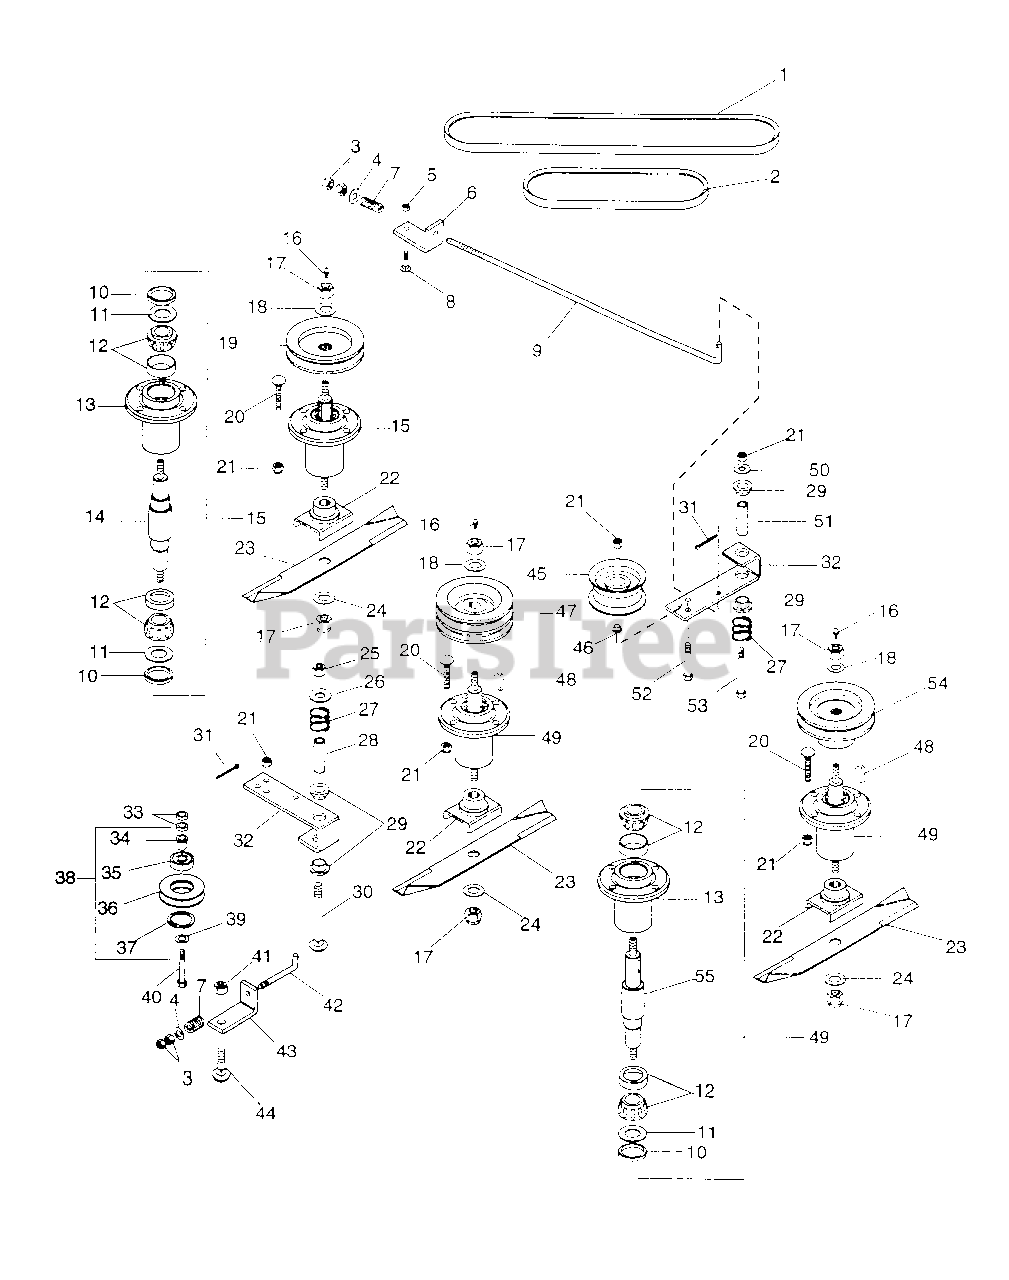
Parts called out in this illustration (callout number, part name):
1	Belt-Mower
2	Belt-mower A44
3	Nut-Hex .375-16
4	Washer-Flat Steel .281 x .625 x .065
5	Nut-Lock-Nylon .312-18 Pl
6	Bracket, Belt Tensioner
7	Spring-Compression .188 x 1.66 x 2.0
8	Bolt-Carriage 5/16-18 x 1.0
9	Rod, Idler L.H.
10	Steel Seal
11	Washer-Flat-Steel .97 x 1.865 x .03
12	Assembly, Bearing Cup & Cone
13	Housing, Bearing
14	Shaft, Spindle R.H.
15	Spindle, Assembly
16	Fitting, Lube 1/8
17	Nut, Lock 5/8-11 Hex W/Insr.
18	Washer-Flat-Steel .687 x 1.312 x .135
19	Sheave, Spindle
20	Bolt-Carriage .38-16 x 1.375
21	Nut-Lock-Nylon .375-16 Pl
22	Weldment, Blade Cradle
23	Blade, 50" Mower
24	Washer-Flat-Steel .656 x 1.312 x .095 Pl
25	Nut-Lock .50-13 Hex Type N
26	Washer-Flat-Steel .531 x 1.250 x .100
27	Spring-Compression
28	Bushing, Steel .560 x .750 x 2.44 St
29	Bushing-Flange .762 x 1.0 x .580 x 1.48 NY
30	Bolt-Carriage .50-13 x 3.50
31	Pin-Cotter .09 x .75 Pl
32	Arm, Idler Pivot
33	Bushing .406 x .750 x .188
34	Bushing-Flange .786 x 1.0 x .79
35	Bearing-Ball 1.85 x .787 x .55
36	Sheave, Idler
37	Snap Ring-Internal 2.054 x .062
38	Assembly, Idler Sheave
39	Washer, Flat .375 x 1.125 x .065
40	Bolt-hex .38-16 x 2.00 Pl Gr. 5
41	Nut-Lock-Nylon .50-13 Pl
42	Rod, Idler
43	Bracket, Belt Tensioner
44	Bolt-Carriage .50-13 x 1.50
45	Idler-Flat 4- .687 x .38
46	Bushing-Flange .406 x .88 x .270 x .140
47	Sheave, Spindle
48	Key, Woodruff 1/4 x 1 Hard #15
49	Assembly, Spindle
50	Washer-Flat-Steel .438 x 1.00 x .083
51	Bushing, Steel .437 x .750 x 2.44 St
52	Bolt-Hex .38-16 x 2.25 Gr.5
53	Bolt-Hex .38-16 x 3.25 Pl Gr. 5
54	Sheave, Spindle
55	Shaft, Spindle
